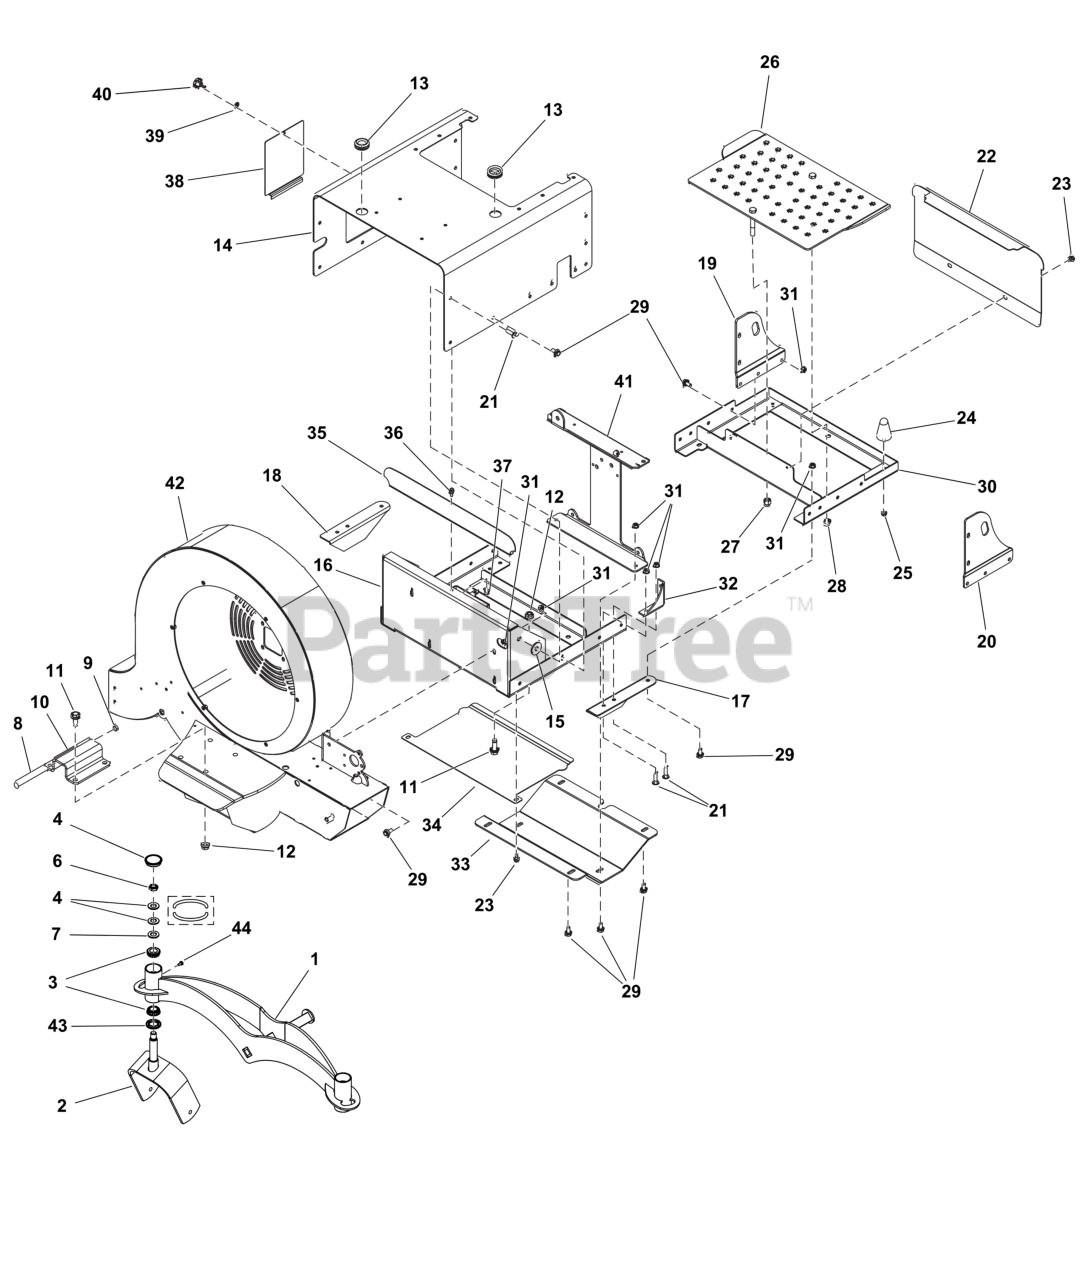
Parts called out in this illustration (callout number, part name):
1	PIVOT, Housing
2	YOKE, Caster
3	BEARING, TAPERED ROLL
5	WASHER, BELLEVILLE
6	NUT - 3/4-16 HEX JAM
7	WASHER, 3/4" SAE
9	RUBBER BAND
13	GROMMET, RUBBER
14	BOX, Motor
16	BOX, FRAME
19	PLATE, TIE DOWN RH
20	PLATE, LEFT
25	NUT, 5/16-18 HEX SERR
30	BOX, FRAME
32	SUPPORT, Transaxle
40	CAPSCREW
41	TRANS, I-Beam
42	HOUSING, BLOWER
43	SEAL, GREASE
44	BOLT - 1/4-28 X 1/2
